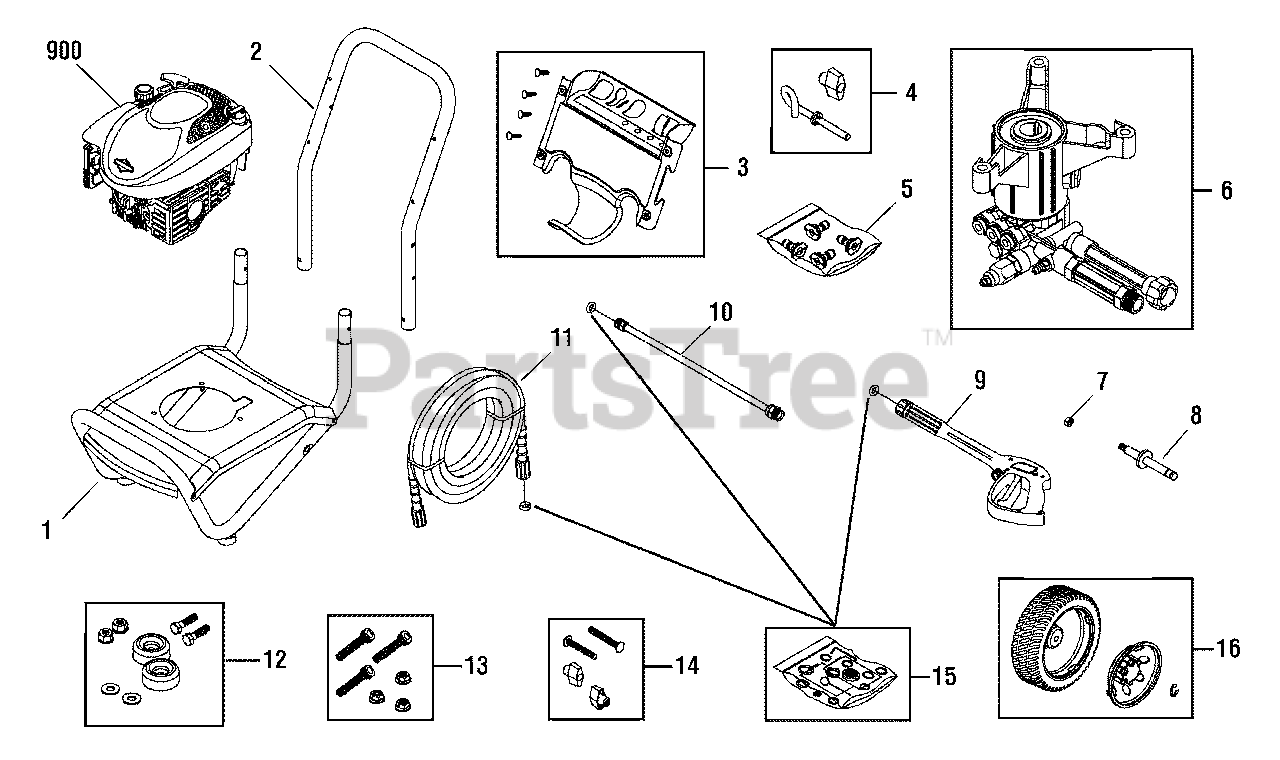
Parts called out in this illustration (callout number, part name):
5	KIT, QC Nozzles
6	PUMP
7	NUT
8	AXLE
9	GUN
10	EXTENSION, QC
11	HOSE
12	MOUNT, Vibration
13	KIT, Hardware, Pump Mounting
14	KIT, Hardware, Handle
15	KIT, O-Rings
